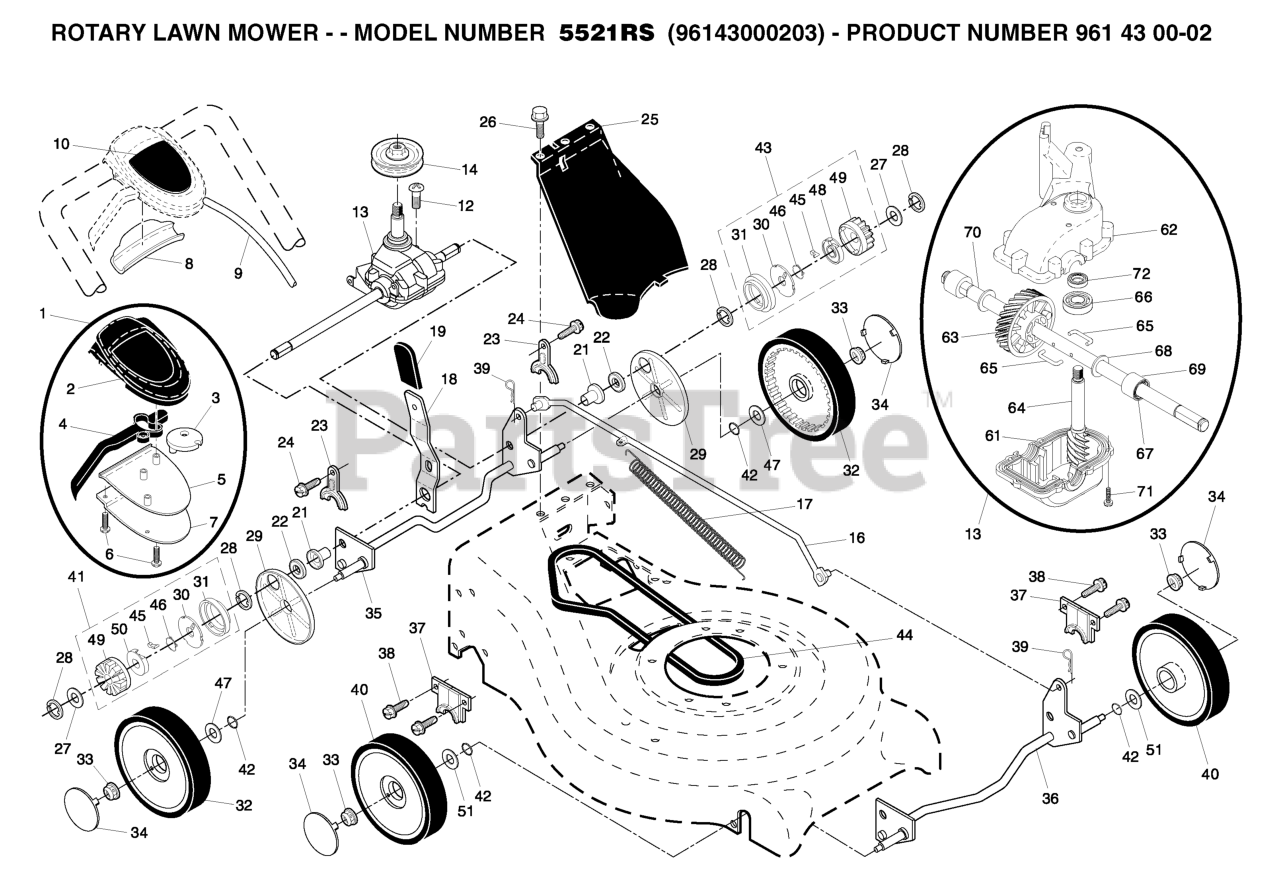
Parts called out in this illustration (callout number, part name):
1	CONTROL.DR.AW.GRY.RWGD.BLACK
2	CASE.TOP.GRAY
3	PULLEY.CAM.DRIVE.CONTROL.HV
4	LEVER, AUTOWALK DRIVE CONTROL
5	CASE BOTTOM
6	SCREW, PHILLIPS HEAD 10 X 5/8
7	BRACKET.DRIVE.CONTROL.MOUNT.BL
8	EZ WALK SNAP COVER PLATE
9	DRIVE CONTROL CABLE
13	TRANSMISSION.21.RWGD.EZ/AW/VS
16	ROD CONNECTING
17	SPRING
18	SPRING.SELECTOR.SPT.21
19	KNOB, SELECTOR SPRING
21	RP BEARING SUPPORT
22	BEARING, BALL
23	BRACKET
25	COVER.DRIVE.21.RWGD.MO
28	E-RING 7/16 RE
29	COVER.DUST.WHEEL
30	DISC.DRIVE.21.EZ-WALK
31	SEAL.PINION
32	WHEEL 9X2
33	HEX FLANGE LOCKNT
34	HUBCAP
35	SHAFT.ASM.REAR.TORQUE
36	SHAFT ASSY FRONT
37	RETAINER.FRONT.SHAFT
39	RETAINER CLIP
40	FRONT.WHEEL.8X2
41	PINION ASSY, RH
42	O-RING
43	PINION ASSY, LH
44	V-BELT
45	PAWL.DRIVE.21.EZ-WALK
46	SPRING, TORSION
47	WASHER FLUT
48	RETAINER.DRIVE.21.EZ-WALK.LT
49	GEAR, PINION
50	RETAINER, DRIVE, RH
51	WASHER.FLAT.1/2
61	CASE, LOWER
62	CASE, UPPER
63	GEAR.24.TOOTH.WALK.MOWER
64	SHAFT INPUT
65	WIRE, FORMED (15966)
67	SEAL.OUTPUT.SHAFT
70	RP.SHAFT.OUTPUT.RGD.VS/EZ
72	SEAL INPUT SHAFT
